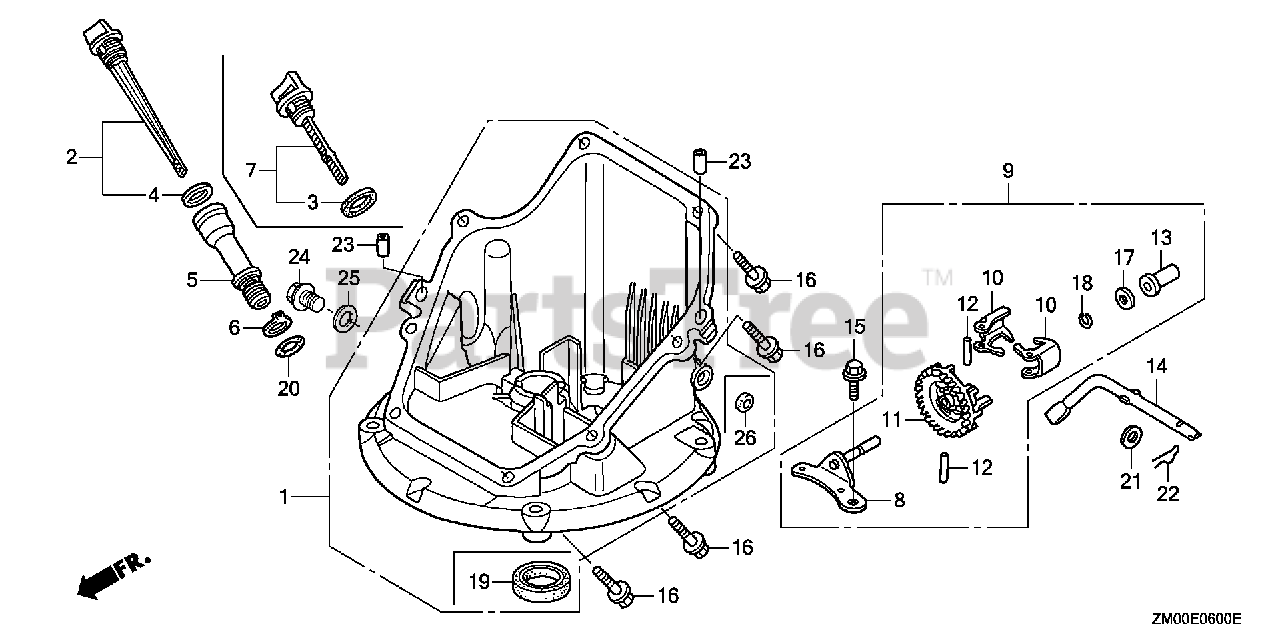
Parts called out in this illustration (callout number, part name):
1	PAN ASSY., OIL
2	GAUGE ASSY., OIL LEVEL
4	GASKET, OIL FILLER CAP
5	EXTENSION, OIL FILLER
6	WASHER, EXTENSION LOCK
8	SHAFT, GOVERNOR HOLDER
9	GOVERNOR ASSY.
10	WEIGHT, GOVERNOR
11	HOLDER, GOVERNOR WEIGHT
12	PIN, GOVERNOR WEIGHT
13	SLIDER, GOVERNOR
14	SHAFT, GOVERNOR ARM
15	BOLT, FLANGE (6X14) (CT200)
16	BOLT, FLANGE (6X25) (CT200)
17	WASHER, THRUST (6MM)
18	CLIP, GOVERNOR HOLDER
19	OIL SEAL (28X41.25X6)
20	O-RING (14.8X2.4) (ARAI)
21	WASHER, PLAIN (6MM)
22	PIN, LOCK (8MM)
23	PIN, DOWEL (8X20)
